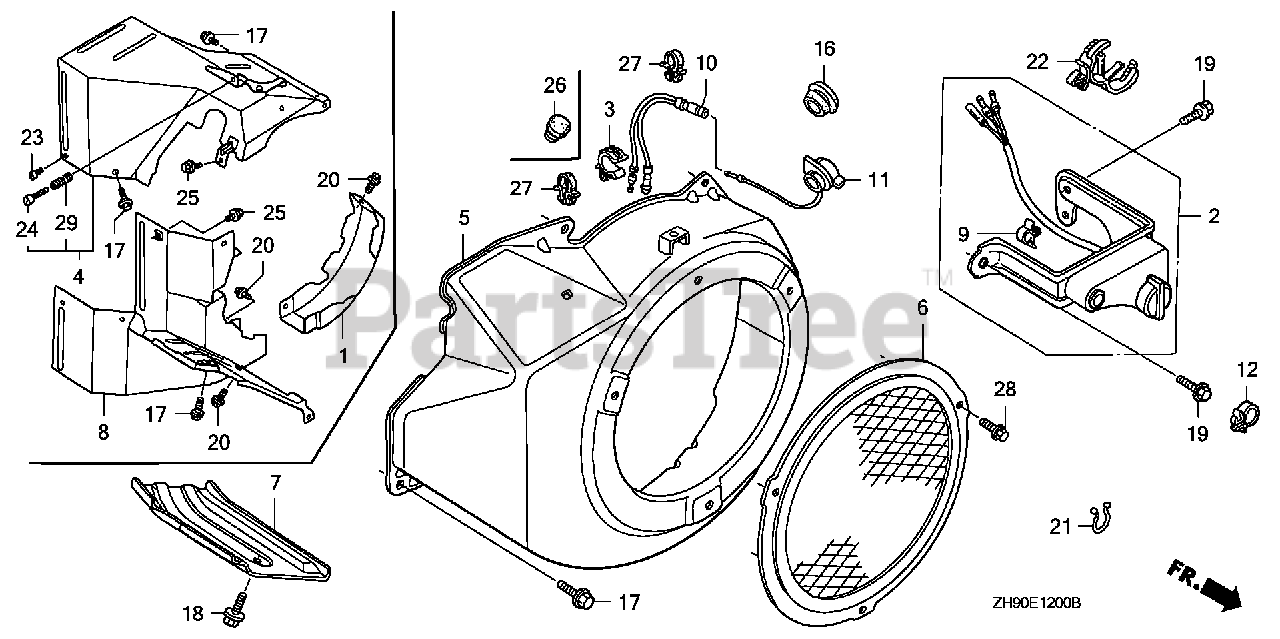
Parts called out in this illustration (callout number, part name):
3	CLIP, TUBE
5	COVER, FAN *R8* (Honda Code 4330981). (BRIGHT RED)
5	COVER, FAN *NH105* (MAT BLACK)
5	COVER, FAN *R280* (Honda Code 7323561). (POWER RED)
7	SHROUD
16	GROMMET, DRAIN HOLE
17	BOLT, FLANGE (6X12) (CT200)
18	BOLT, FLANGE (6X12) (CT200)
